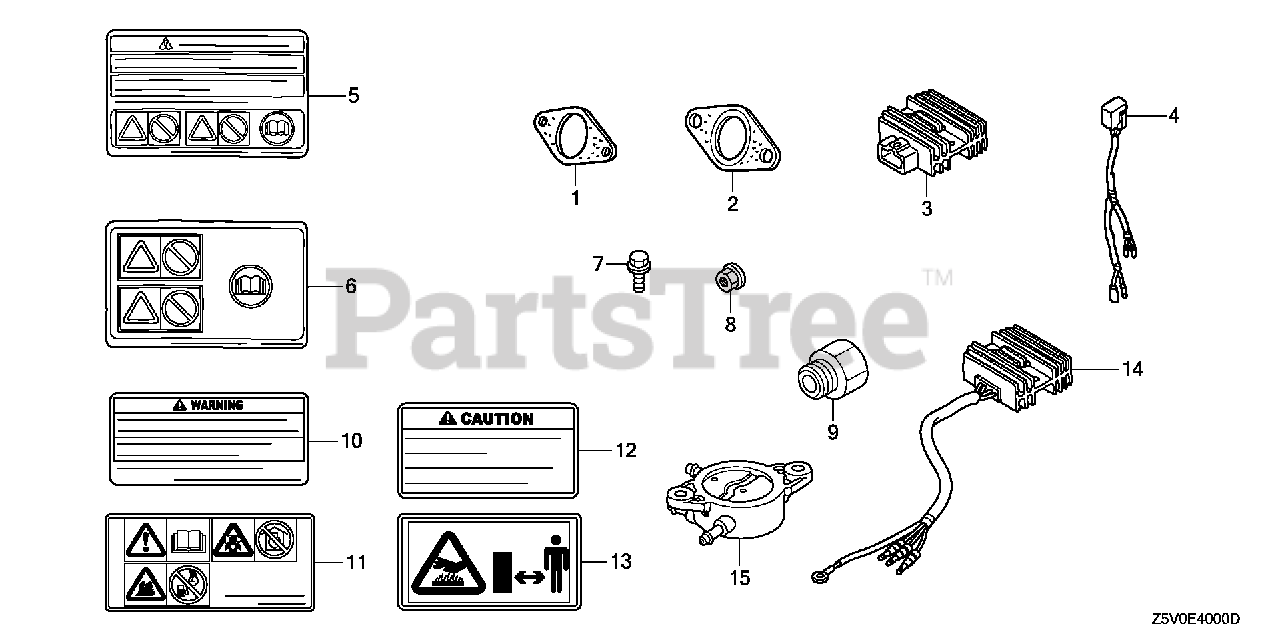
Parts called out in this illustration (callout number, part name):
3	RECTIFIER ASSY., REGULATOR (10A)
5	MARK, OPERATOR CAUTION (FRENCH)(MADE IN THAI)
9	ADAPTER, OIL DRAIN EXTENSION
10	MARK, OPERATOR CAUTION (FRENCH)(MADE IN THAI)
